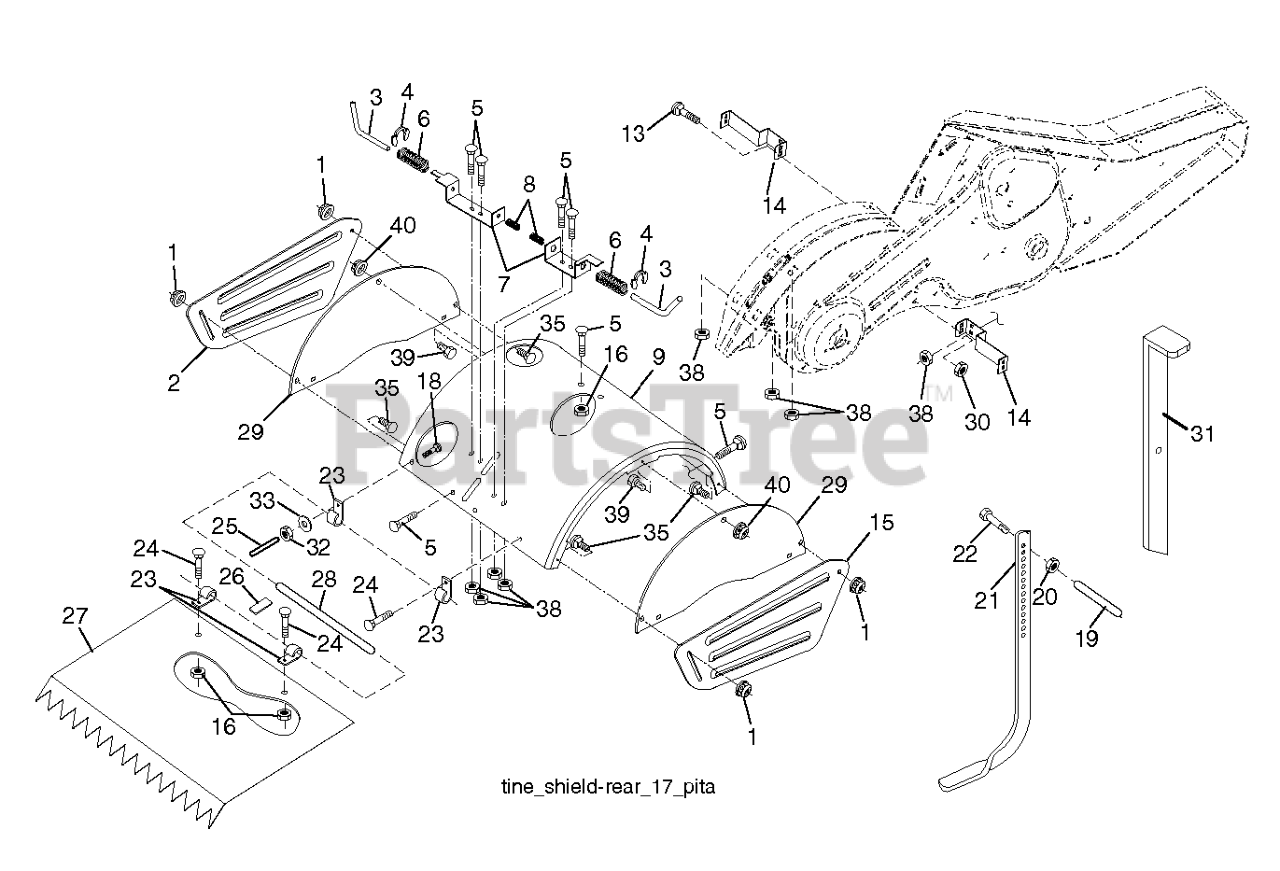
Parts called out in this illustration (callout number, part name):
1	NUT.FLANGE.5/16
2	SHIELD.PNT.SIDE.OUTER.LH.ORANG
3	STAKE PIN TI
4	RING, KLIP
5	BOLT, RDHD SQNK 5/16-18 X 3/4
7	BRACKET
8	SPRING CRT
9	SHIELD.TINE.DRT17.TILLER.ORANG
13	BOLT.CARRIAGE.5/16-18
14	BRACKET.TINE.SHIELD.BLACK
15	SHIELD.SIDE OUTER.RH.ORANGE
16	NUT T
20	NUT.HEX.3/8-16UNC
21	REPL BY 532 10 21-56
22	BOLT.375-16
24	BOLT
25	VINYL CAP TI
26	PAD IDLER TI
27	SHIELD.LEVELING.17".ORANGE
28	PIN.HINGE.TILLER
29	SHIELD.TINE.SIDE.ORANGE
30	LOCKNUT-FLANGE 5/16-18
31	STAKE.DEPTH.DRAG.BLACK.TILLER
32	NUT
33	LOCKWASHER
35	BOLT.CARR.5/16-18X5/8.SHORT
38	NUT
39	BOLT.HEX.HD.WASHER.5/16-18X.75
40	NUT.SPEED.5/16-18
